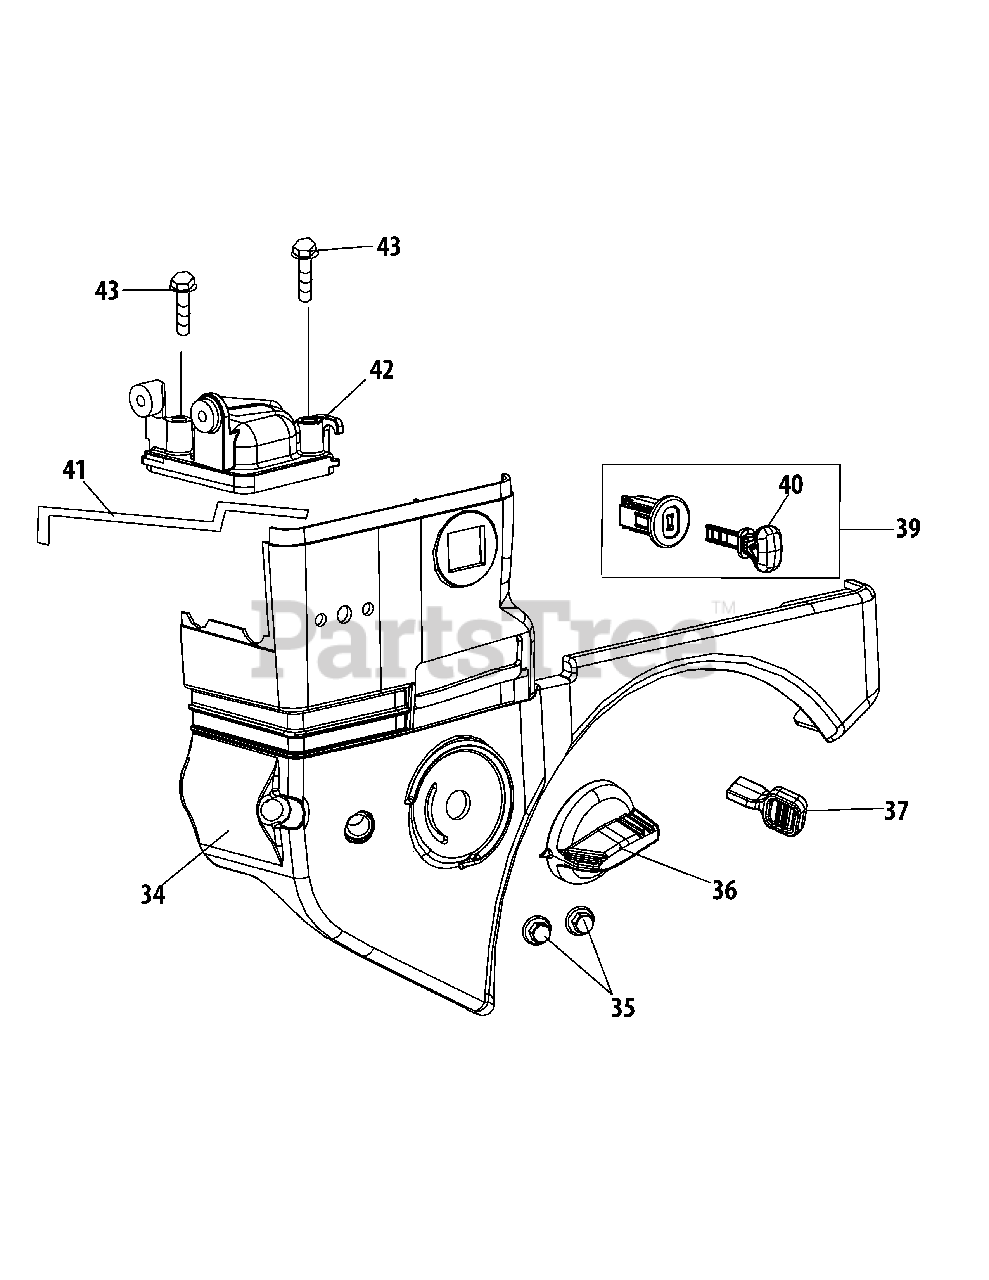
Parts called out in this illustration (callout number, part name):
34	Shroud-Engine
36	Choke Knob
37	Throttle Knob
39	Switch-Ignition
40	Ignition Key Switch
41	Push Rod-Choke
42	Air Filter Heating
43	Bolt-M6 1X28M Spec
